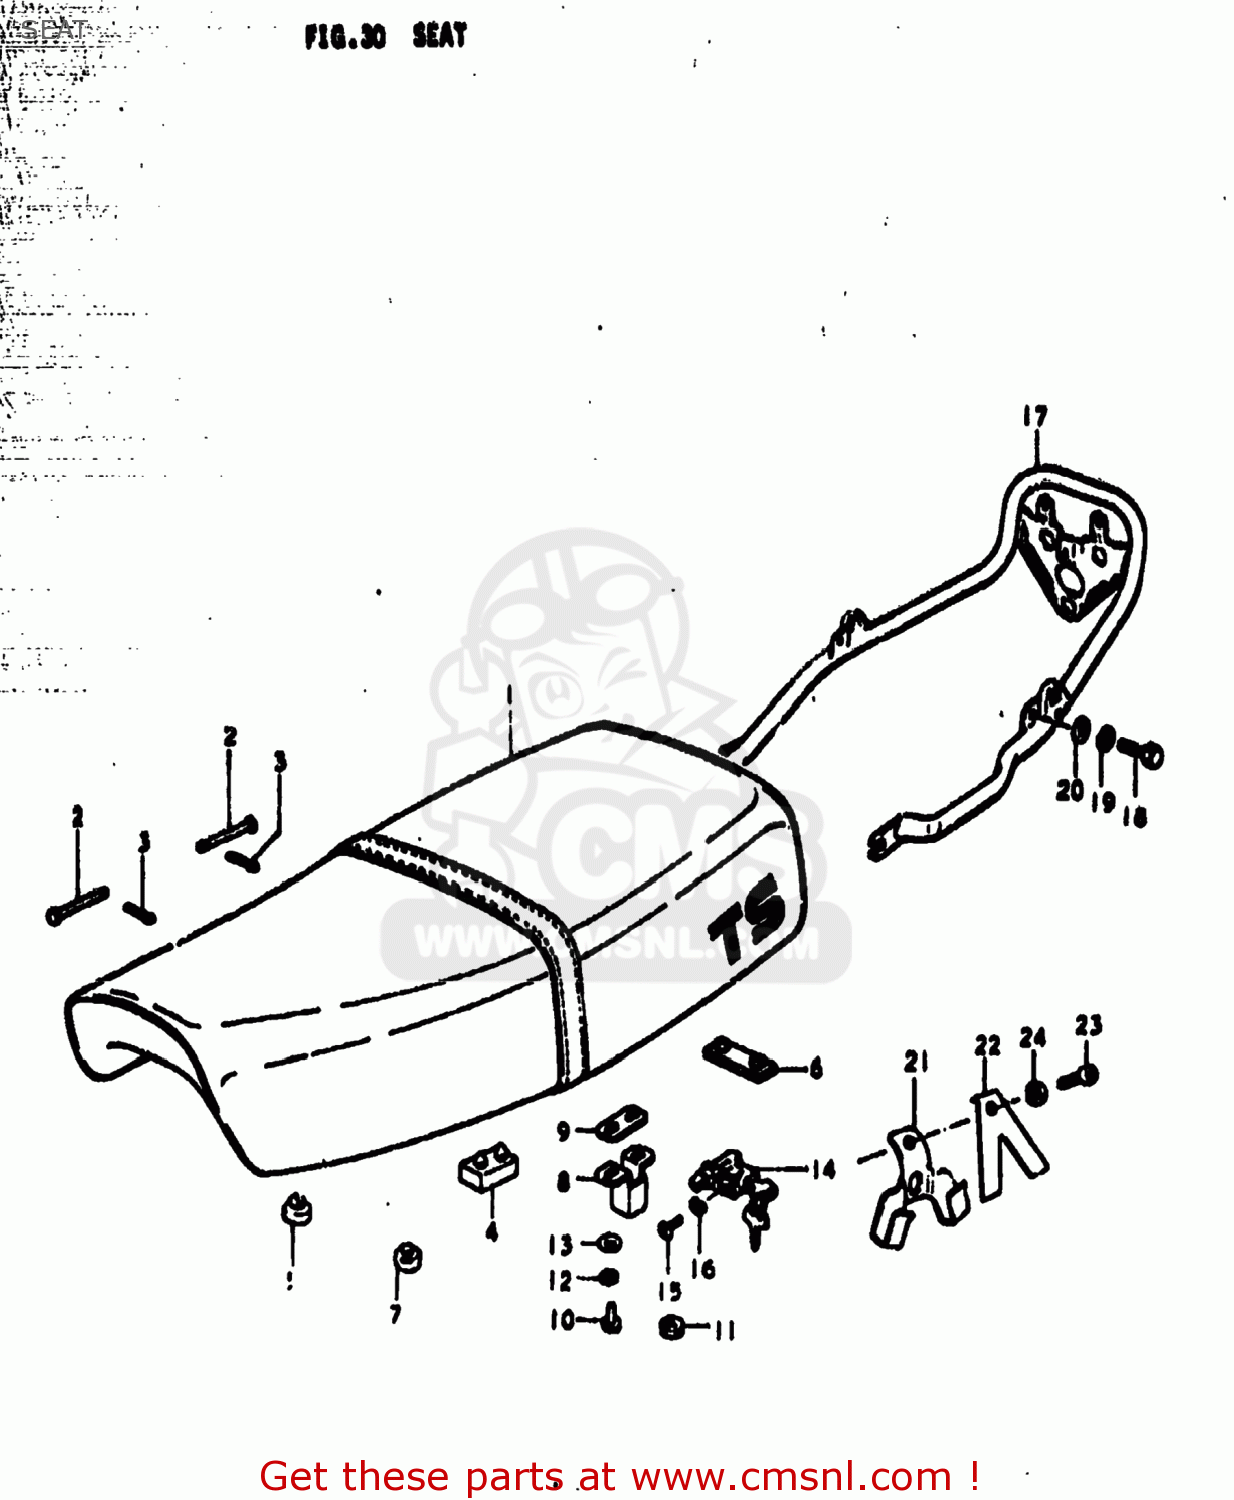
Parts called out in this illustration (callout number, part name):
1	SEAT ASSEMBLY
2	PIN
3	PIN
4	CUSHION
5	CUSHION(11.5X22X20)
6	CUSHION
7	CUSHION
8	PLATE,CLAMP GUIDE
9	WASHER(8.5X18X1)
10	BOLT
11	NUT
12	LOCK WASHER
13	WASHER
14	LOCK ASSY,SEAT
15	SCREW
16	LOCK WASHER
17	BAR,REAR COMBINATION LAMP
18	BOLT
19	LOCK WASHER
20	WASHER
21	HOLDER,HELMET
22	SPRING OPT
23	SCREW 6X12
24	LOCK WASHER
